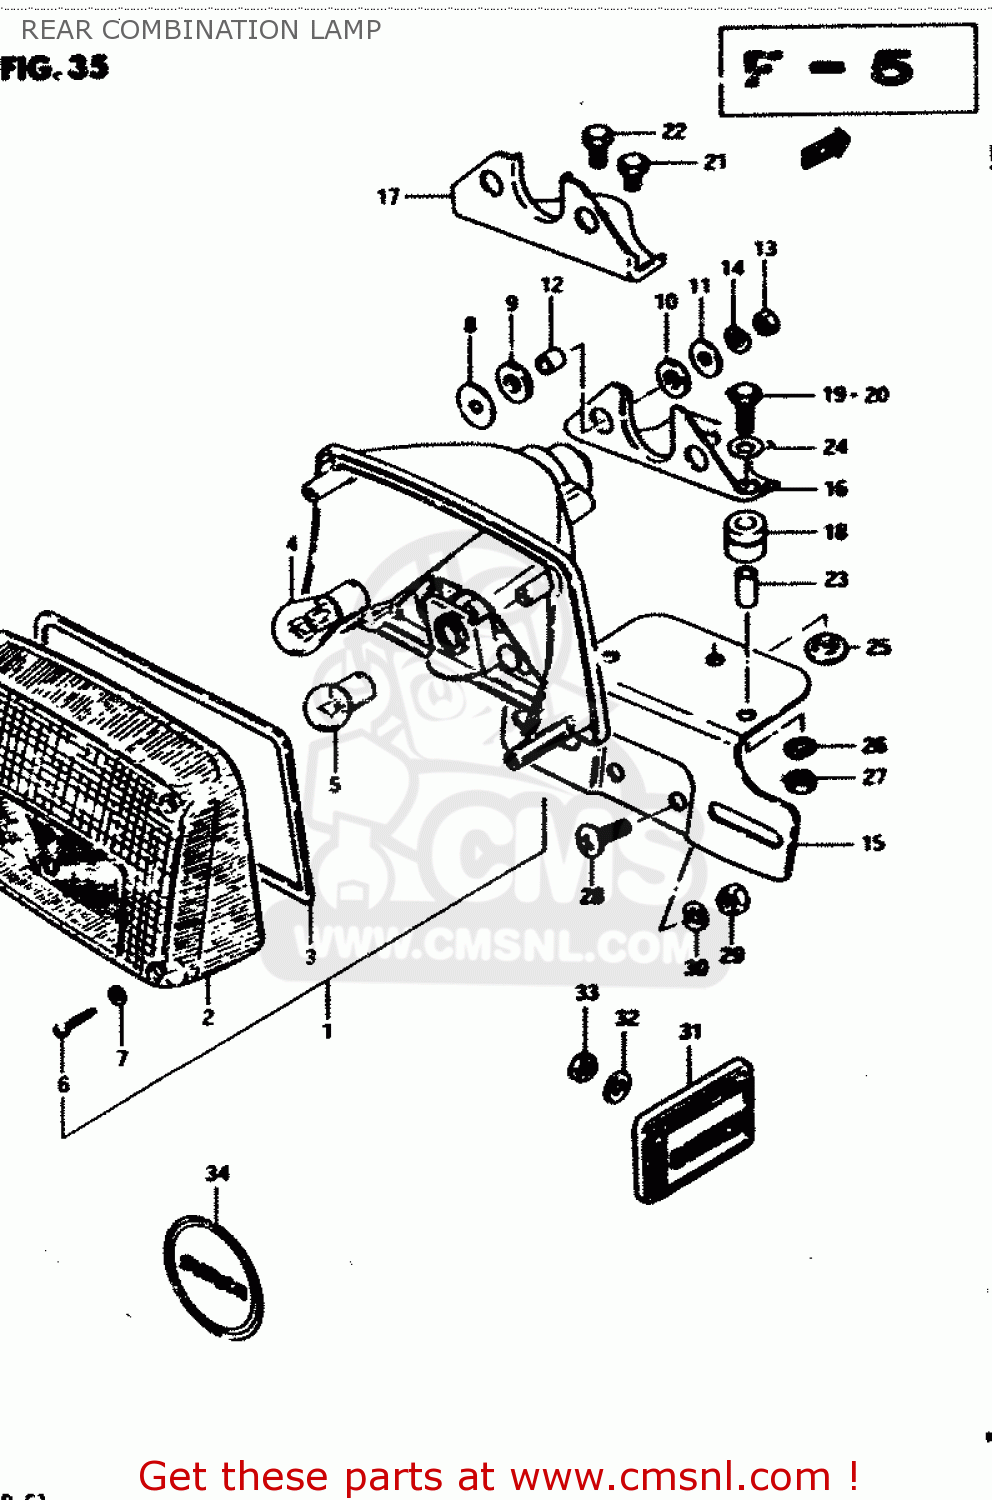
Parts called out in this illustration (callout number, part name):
1	LAMP ASSEMBLY,REAR COMBINATION
2	LENS
3	GASKET (NAS)
4	BULB(12V23W)
5	BULB
6	SCREW,REAR COMBINATION LAMP
7	GASKET (NAS)
8	WASHER
9	CUSHION
10	CUSHION
11	WASHER(6,5X22X1.6)
12	SPACER(6.1X9X7.5)
13	NUT
14	LOCK WASHER
15	BRACKET, LICENCE PLATE
16	BRACKET,LICENSE PLATE
17	BRACKET,REAR COMBINATION LAMP
18	CUSHION, BRACKET
19	BOLT
20	BOLT
21	BOLT
22	BOLT, UPPER
23	SPACER (6.4X9X15.5)
24	WASHER
25	WASHER
26	LOCK WASHER
27	NUT
28	SCREW
29	NUT
30	LOCK WASHER
31	EMBLEM, REAR SIDE
32	WASHER
33	NUT
34	EMBLEM, REAR
